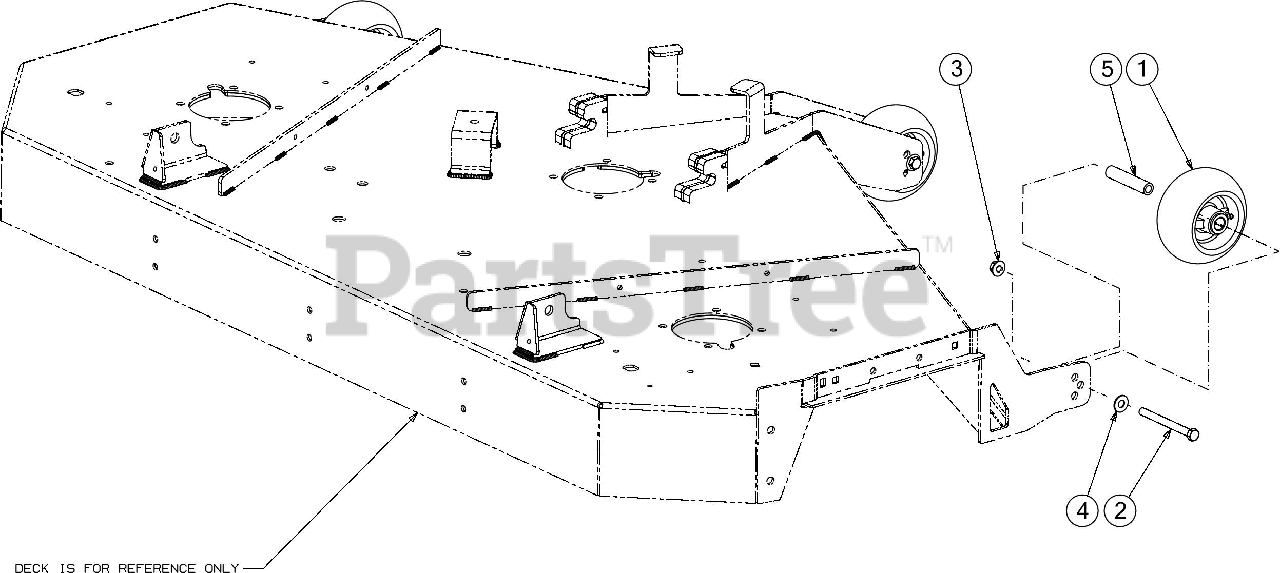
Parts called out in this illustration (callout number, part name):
1	WHEEL ASSEMBLY 5"
1	FLANGE BEARING
1	GREASE FITTING
2	HEX SCREW 3/8-16 x 4.00
4	FLAT WASHER
5	WHEEL SPACER .38ID x 3.04LG
